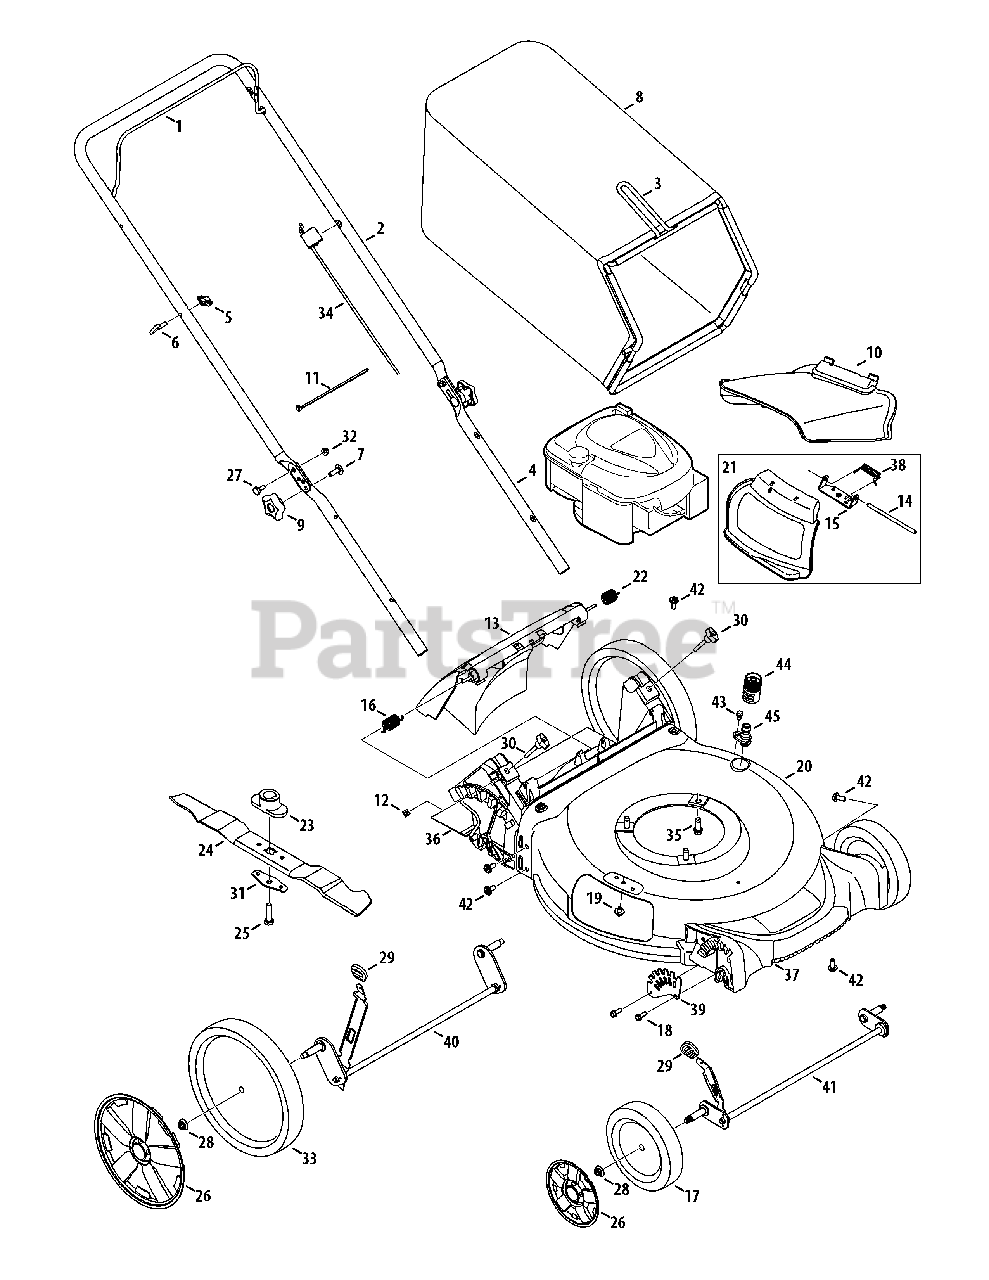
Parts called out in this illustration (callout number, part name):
1	Blade Control
2	Upper Handle
3	Grass Catcher Frame
4	Lower Handle
5	Wing Nut
6	Rope Guide
7	Carriage Screw, 5/16-18
8	Grass Bag
9	Hand Knob
10	Side Chute
11	Cable Tie
12	Nut, Sq., 1/4-20
13	Rear Discharge Door Assembly
14	Hinge Pin
15	Chute Deflector Bracket
16	Torsion Spring - RH
17	Wheel, 7 x 2
18	Screw, 1/4-15 x .750
19	Screw, 1/4-20 x .500
20	Deck - 21"
21	Hinged Mulch Plug Assembly
22	Torsion Spring - LH
23	Blade Adapter
24	Mulching Blade
25	Screw , 3/8-24 x 1.50
26	Hub Cap - Front
26	Hub Cap - Rear
27	Sldr. Screw, .375 x .126 x 1/4-20
28	Flange Lock Nut, 3/8-16
29	Adjustment Lever Knob
30	Wing Knob
31	Blade Bell Support
32	Nut, Flange Lock, 1/4-20
33	Wheel, 11 x 2
34	Control Cable
35	TT Screw, 3/8-16 x 1.0
36	Trail shield
37	Front Cover
38	Torsion Spring
39	Front Height Adjuster Plate
40	Rear Axle Assembly
41	Front Axle Assembly
42	Screw, 5/16-14 x .750
43	Shldr. Screw, 1/4-20 x .50
44	Water Nozzle Adapter
45	Deck Wash Nozzle
